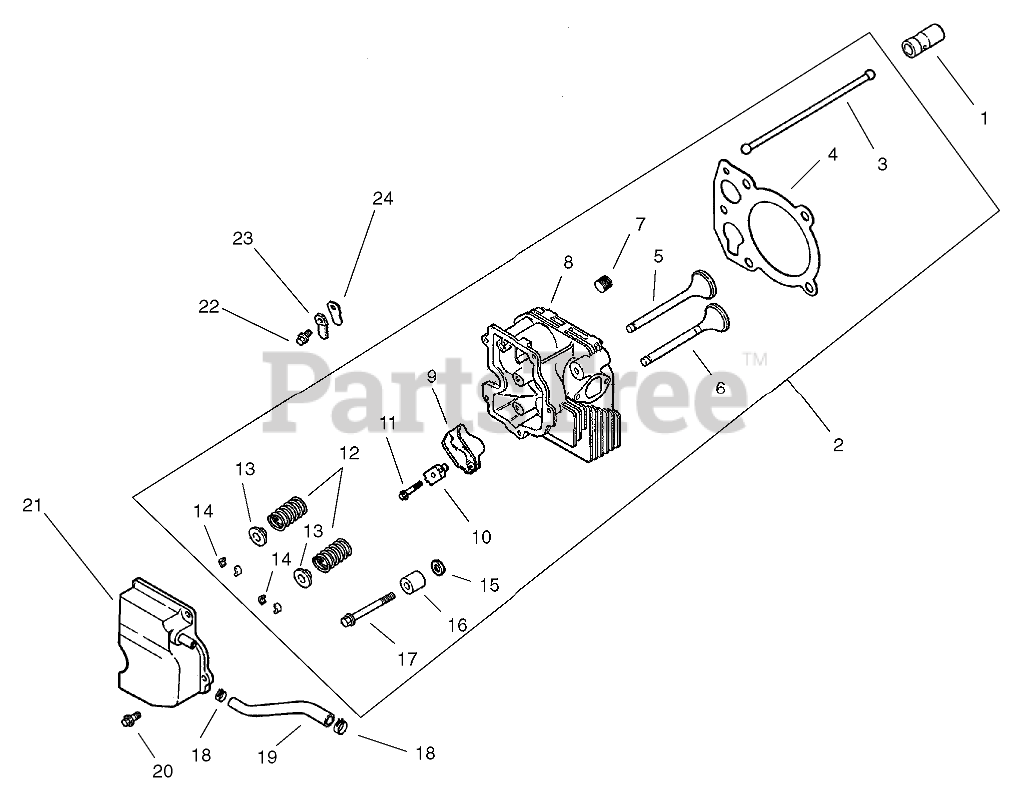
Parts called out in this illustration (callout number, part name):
1	Lifter-Valve
2	Kit, cylinder head (Includes 3-17, carburetor gasket (2), air cleaner base gasket, exhaust manifold gasket)
3	Rod-Push
4	Gasket-Head, Cylinder
5	Valve-Intake (STD)
6	Valve-Exhaust (STD)
7	PLUG-PIPE, COUNTERSUNK (1/8)
8	Cylinder Head
9	ARM-ROCKER
10	Pivot-Arm, Rocker
11	SCREW-FLANGE (M6X1.0X34)
12	Spring-Valve
13	CAP-SPRING, VALVE
14	RETAINER KIT
15	Washer-Flat (1/2)
16	Spacer-Head Bolt (Exhaust Port)
17	Screw, M10x1.5x81
18	CLAMP-HOSE, SPRING (1/2)
19	Hose-Breather
20	SCREW-HHFTF (M6X1.0X20)
21	Cover-Valve w/Nipple
22	SCREW-HHFTF (M5X.80X10)
23	Retainer-Reed, Breather
24	REED-BREATHER
